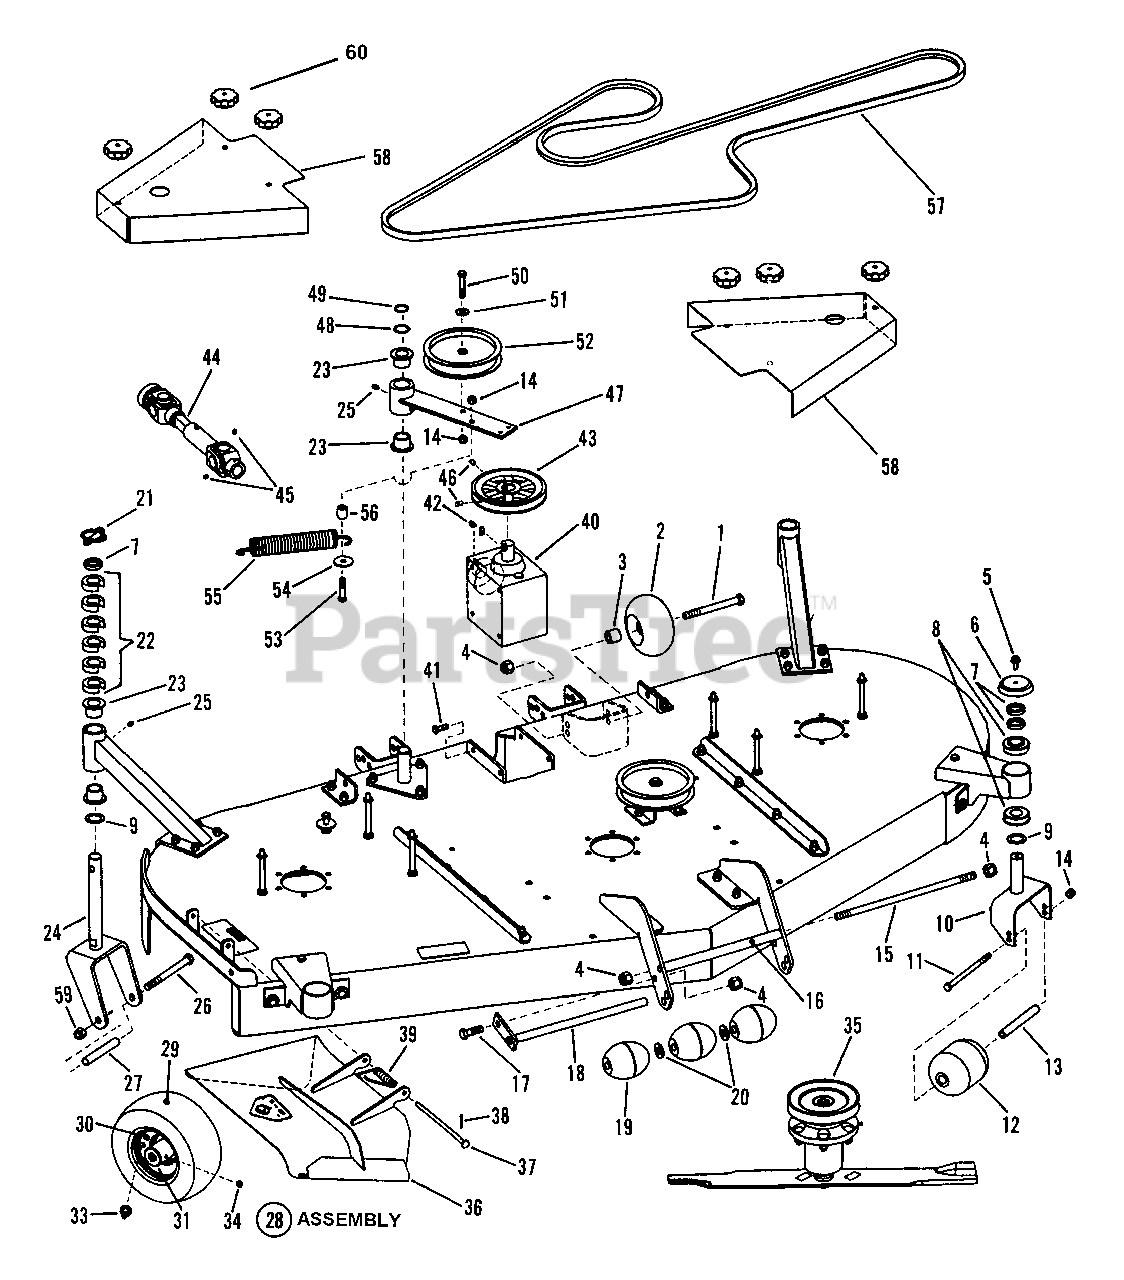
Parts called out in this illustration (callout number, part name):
1	BOLT, 1/2-13 X 5 GD5 YZ
2	GAGE WHEEL
3	SPACER, Gage Wheel
4	NUT, 1/2-13 Hex Nyloc
5	SCREW, 5/16-18 x 3/4" Hex Washer Self-Tap
6	CAP, Caster Shaft
7	SPACER, 1" x 1 3/8 x .30" (PM)
8	BEARING, Flanged Radial 1 x 2 x 23/32" Double Seal
9	BUSHING, Machine 1" I.D.
10	WELDMENT, Gauge Wheel Caster
11	BOLT, 3/8-16 X 6" GD5 CZ
12	ROLLER, 3-3/4 x 4-13/16" Nylon
13	TUBE, Axle
14	NUT, 3/8-16 HEX NYLON LOCK
15	ROD, Threaded Roller
16	TUBE, Roller
17	BOLT, 1/2-13 X 1-1/2 GD5 CZ
18	WELDMENT, Pivot Pin
19	ROLLER, Low Density Polyethylene
20	WASHER, 5/8" SAE Flat
21	PIN, 7/16" Linch
22	SPACER, Caster
23	BUSHING, Caster
24	WELDMENT, Caster Yoke
25	FITTING, 1/4-28, Straight, Grease
26	BOLT, 1/2-13 X 5-1/2" GD5 YZ
27	SLEEVE, Axle
28	ASSEMBLY, Wheel/Tire
29	TIRE, 9 x 3.50-4, 4 Ply Smooth
30	RIM, One Piece Steel, White
31	BEARING, Flanged
33	VALVE, Air
34	FITTING, 1/4-28, 45 Degree, Grease
35	GROUP, Spindle
36	WELDMENT, Chute Deflector
37	HINGE PIN, Chute
38	PIN, 3/32 x 1" Cotter
39	SPRING, Chute
40	GEARBOX, Right Angle 1.5:1
41	BOLT, 3/8-16 X 1" GD5 CZ
42	KEY, 1/4 x 7/8" Woodruff
43	PULLEY, Cast 5.95 O.D.
44	DRIVESHAFT, Telescoping
45	SCREW, 3/8-16 x 3/8" Set
46	SCREW, 5/16-18 x 5/8" Socket Head Set
47	WELDMENT, Idler Arm
48	WASHER, 1-1/32 I.D. x 1-1/4" O.D. Flat
49	E-RING, 1"
50	BOLT, 3/8-16 X 2, GD5, CZ
51	WASHER, 3/8" USS
52	PULLEY, 5-1/2" O.D. Idler
53	SCREW, 3/8-16 x 1-3/4" Hex Head Cap, Grade 5
54	WASHER, 13/32 I.D. x 1-1/2" O.D. Flat
55	SPRING, Extension
56	SPACER, 1/2 I.D. x 3/4" O.D. x .83
57	BELT, 152" HB Section
58	GUARD, Pulley
59	NUT, 1/2-13 HEX NYLON LOCK
60	KNOB
